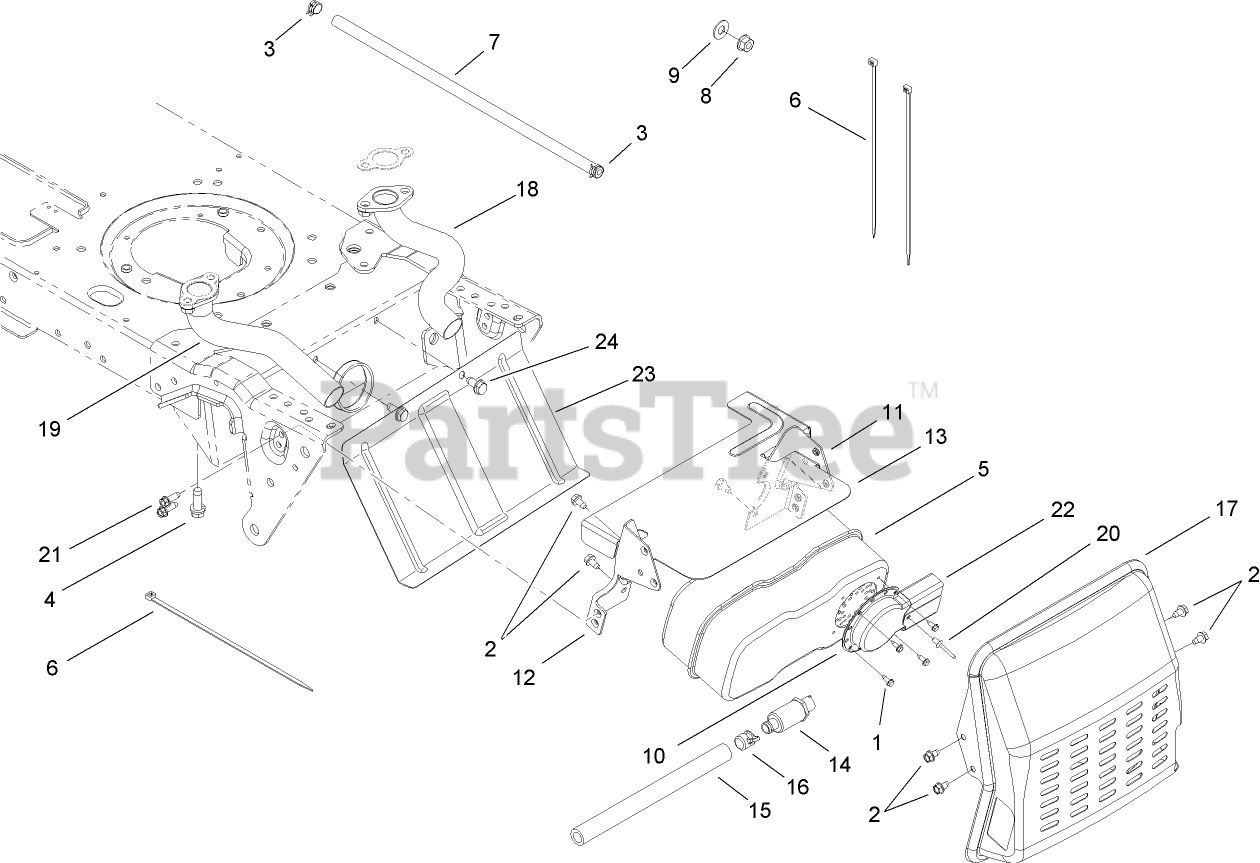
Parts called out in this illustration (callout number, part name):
1	SCREW-HWHTF
2	SCREW-HWHTF
3	CLAMP-HOSE
4	SCREW-TAP
5	MUFFLER-INLET, DUAL
6	TIE-CABLE
7	HOSE-FUEL
8	NUT-LOCK, FLANGE
9	WASHER-FLAT
10	DEFLECTOR-MUFFLER
11	BRACKET-MUFFLER, LH
12	BRACKET-MUFFLER, RH
13	SHIELD-HEAT
15	HOSE-DRAIN
17	MUFFLER HEAT SHIELD ASM
18	PIPE-EXHAUST, LH
19	PIPE-EXHAUST, RH
20	RIVET-POP
21	SCREW-TAP
22	DEFLECTOR-MUFFLER, LONG
23	SHIELD-HEAT, TRACTOR
24	SCREW-HWH
